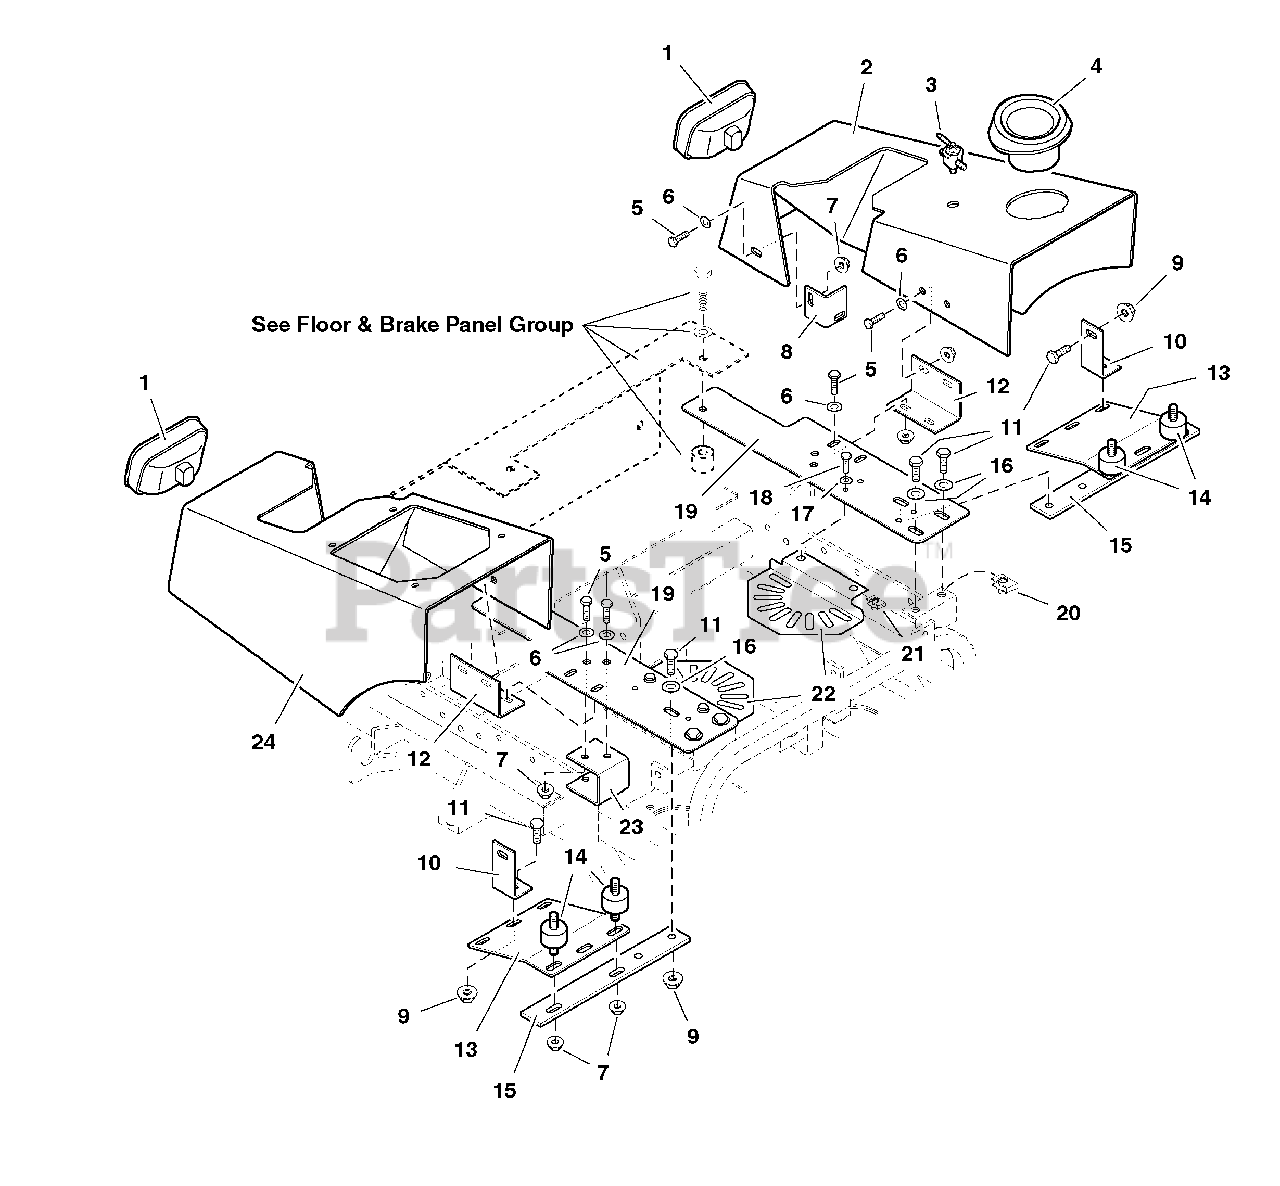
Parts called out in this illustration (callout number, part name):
1	HEADLIGHT ASSEMBLY, Complete
2	CONTROL COVER-RH
3	VALVE, Fuel Shut Off
5	CAPSCREW, Hex Hd, 5/16-18 x 3/4
6	WASHER, 5/16
7	NUT, Hex, Serrated Flange, 5/16-18
8	SUPPORT, Cover-RH
9	NUT, Hex, Serrated Flange, 3/8-16
10	SUPPORT, Control Cover
11	CAPSCREW, Hex Hd, 3/8-16 x 3/4
12	SUPPORT, Control Cover
13	DEBRIS GUARD
14	RUBBER ISOLATOR
15	TANK MOUNT BAR
16	WASHER, 3/8
17	WASHER, 1/4 SAE (5025154)
18	CAPSCREW, Hex Hd, 1/4-20 x 3/4
19	FAN SHIELD MOUNT
20	BODY CLIP, 3/8-16
21	BODY CLIP, 1/4-20
22	FAN SHIELD
23	MOUNT, Oil Filter
24	CONTROL COVER-LH
